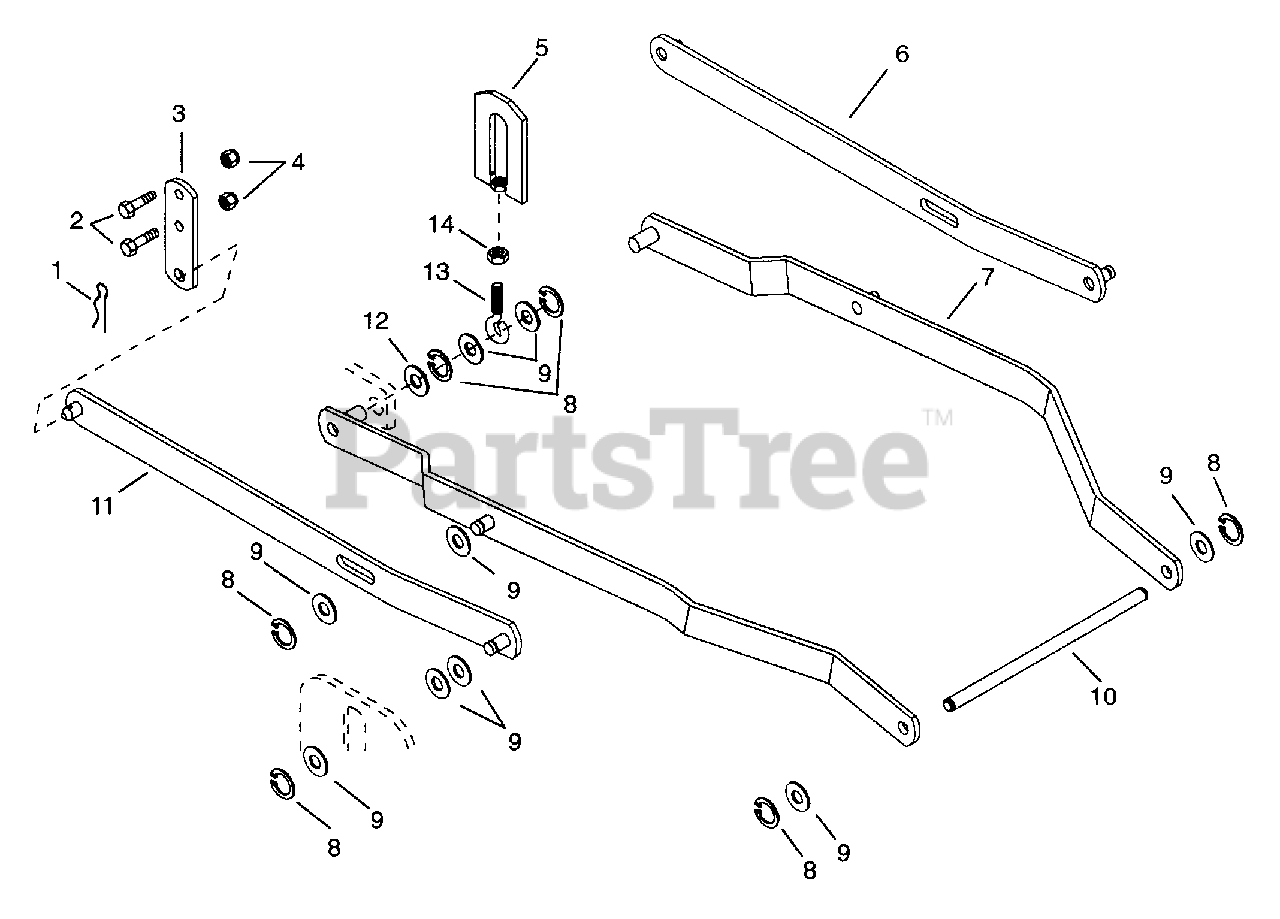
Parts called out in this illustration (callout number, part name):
1	PIN-HAIR EXT .12X.31X2.37 PL
2	BLT-HEX .38-16X.75 PL GR5
3	HANGER BRACKET
4	NUT-LK TOP .375-16 GR C YWZC
5	LINK, ADJUSTMENT
6	REAR HANGER LH
7	LH LIFT ARM
8	RG-RTNG-EXT .500X.050 (SNAP)
9	WSHR-FL-STL .531X1.062X.095 PL
10	PIN
11	REAR HANGER RH
12	WSHR-FL-STL .531X1.250X.100 PL
14	NUT-JAM .375-16 PL
15	RH LIFT ARM
